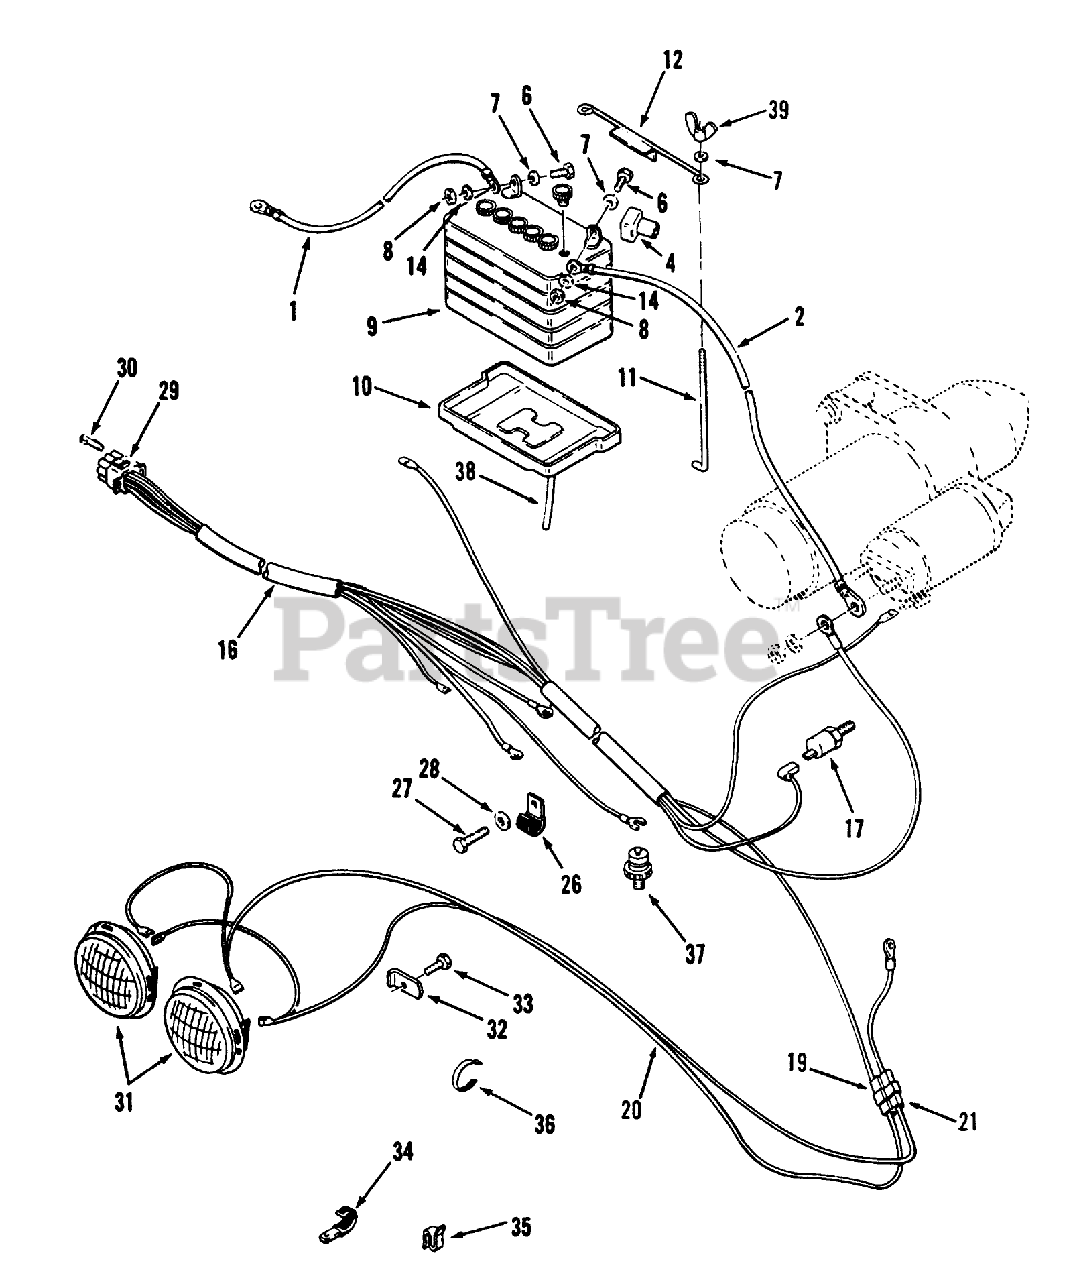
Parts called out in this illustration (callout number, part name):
1	ASS'Y-WIRE
2	ASS'Y-WIRE
6	SCREW-HH
7	WASHER-FLAT
8	NUT-LOCK, NI
10	THRUST WASHER
11	HOOK-BATTERY RETAIN
12	HOLDDOWN-BATTERY
14	WASHER-LOCK
19	MALE CONNECTOR
21	CONNECTOR BODY
26	CLIP-WIRE
27	SCREW-HWH
30	CONTACT SOCKET
31	HEADLAMP
32	LOCK-HEADLIGHT
33	Bolt
34	CLIP
38	TUBE-21" BATTERY DRAIN
39	NUT-WING
